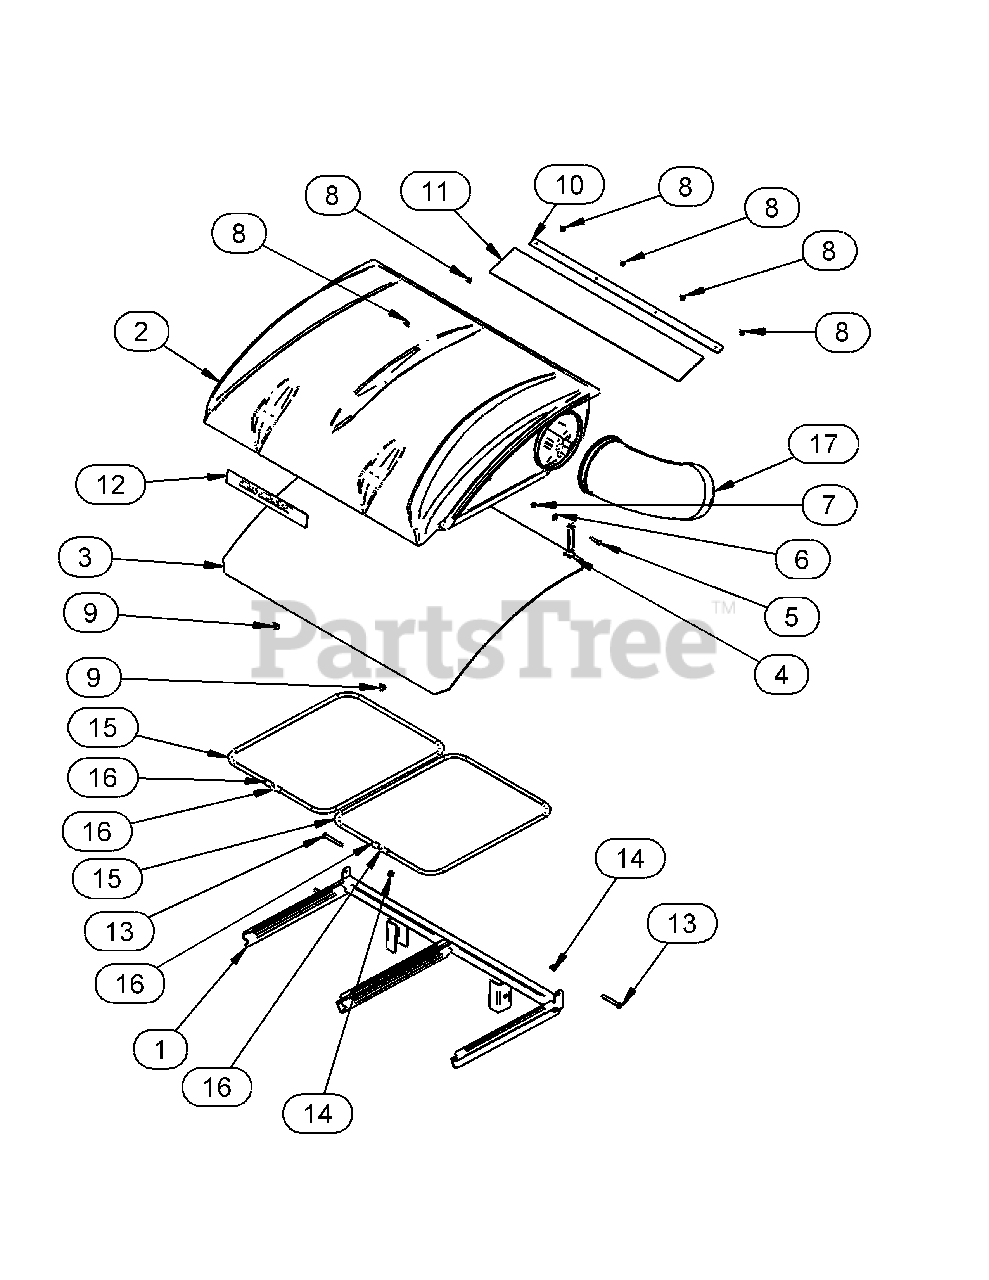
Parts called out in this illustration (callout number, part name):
1	2 BAG FRAME ASSY
2	PRO 2 BAGGER TOP
4	SHORT RUBBER STRAP W/ S HOOK
5	1/4"-20 x 1-1/4" CARRIAGE BOLT
6	1/4" FLAT WASHER .75 OD x .314 ID x .060
7	1/4"-20 NYLOC NUT
8	BLACK PLASTIC RIVET
9	BLACK PANEL RETAINER
10	DUST GUARD BRACE
11	DUST GUARD
12	CUB CADET LOGO
13	5/16"-18 x 2-1/2" ALL THREAD HHCS
14	5/16"-15 NYLON FLANGE LOCKNUT
16	BAG RING END CAP
